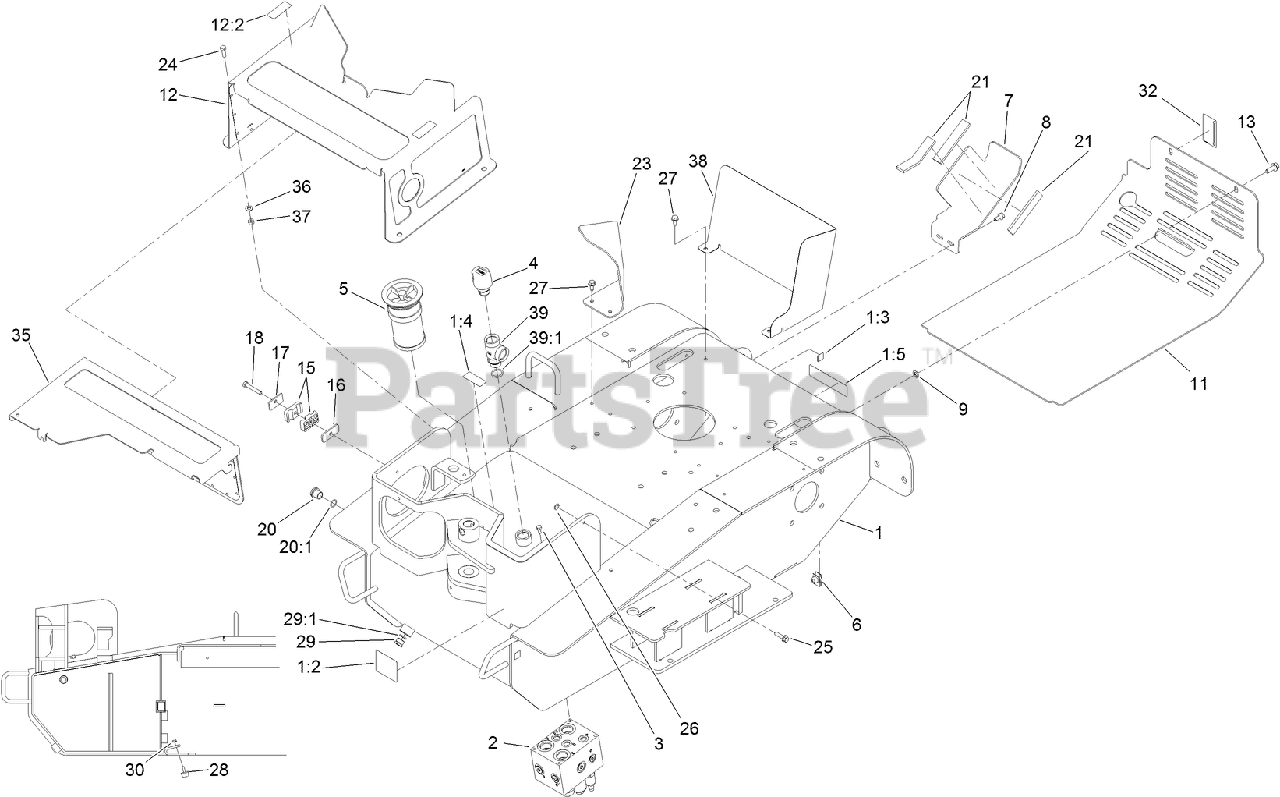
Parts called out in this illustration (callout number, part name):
1	FRAME-MAIN
1:2	DECAL-WARNING
1:3	DECAL-POINT, LIFT
1:4	DECAL-OIL, HYD
1:5	DECAL-DANGER
2	VALVE-CUTTER
3	SCREW-HH
4	BREATHER
5	CARTRIDGE-FILTER
6	NUT-TINNERMAN
7	BRACKET-TANK
8	SCREW-HHF
9	NUT-PUSH
11	COVER-REAR
12	MUFFLER COVER ASM
12:2	DECAL-SURFACE, HOT
13	SCREW-HHF
15	CLAMP-TUBE
16	PLATE-CLAMP
17	COVERPLATE
18	SCREW-HH
20	SIGHT GLASS ASM
20:1	O-RING
21	PAD-FOAM
23	PLATE-DEFLECTOR, RH
24	SCREW-HH
25	SCREW-HHF
26	NUT-PUSH
27	SCREW-HWHTF
28	BUMPER
29	PLUG-HEX
29:1	O-RING
30	NUT-HF
32	DECAL-BRAKE, PARKING
35	COVER
36	WASHER-PLAIN
37	NUT-LOCK, NI
38	BRACKET-DEFLECTOR
39	FITTING-TEE
39:1	O-RING
